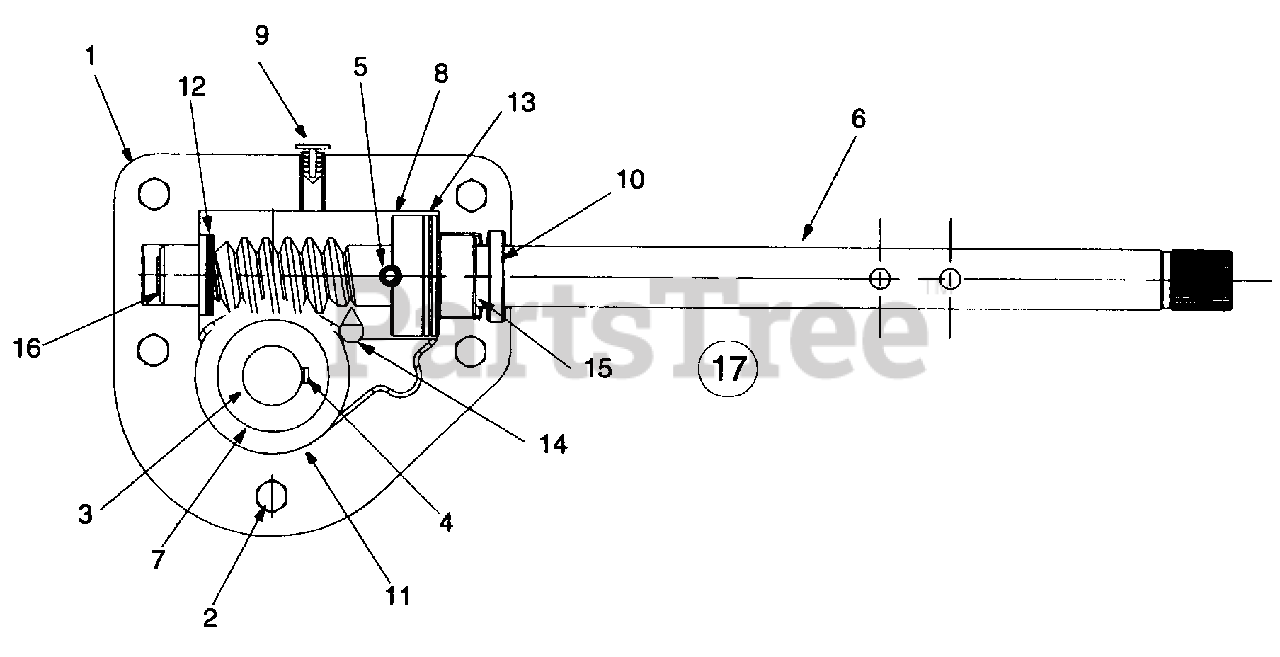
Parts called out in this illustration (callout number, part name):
1	Housing - L.H.
2	Hex Screw 1/4-20 x .75
3	Spiral Axle 24"
4	Key
5	Pin-Spiral
6	Shaft-Worm
7	Gear-Worm
8	Collar-Thrust
11	Washer-Flat
12	Washer-Flat
13	Washer-Flat
14	Grease
15	Bearing-Flange
16	Bearing-Flange
17	Ass'y. Complete 24"
